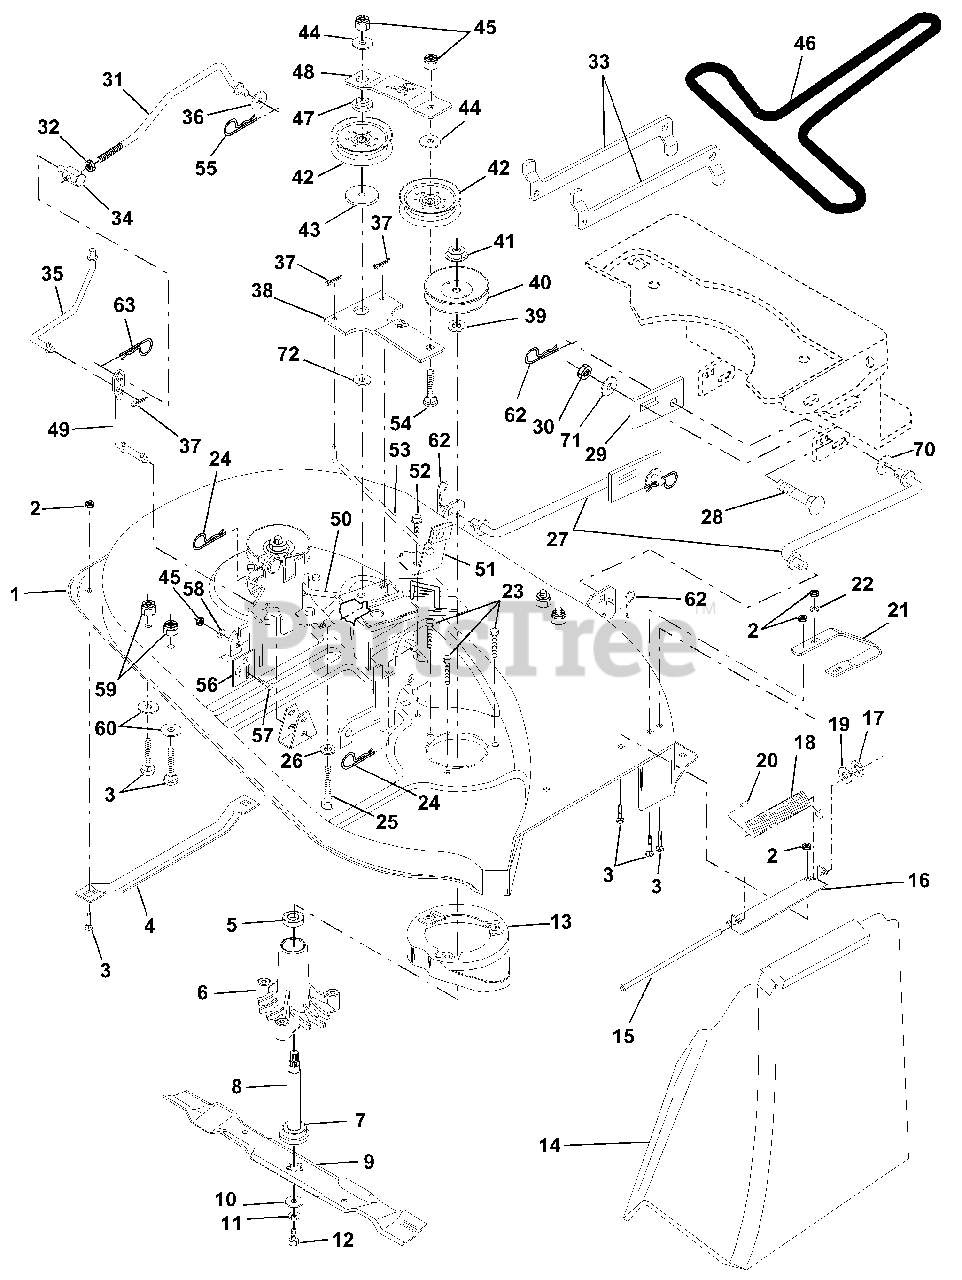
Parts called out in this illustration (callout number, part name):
1	Mower Deck Assembly
2	Nut, Lock Hx w/Ins 5/16-18
3	Bolt, Carriage 5/16-18 x 3/4
4	Runner, L.H.
6	Housing, Mandrel
8	Shaft and Bearing Assembly, Mandrel
10	Washer, Hardened
11	Washer, Lock 3/8
12	Bolt, Hex 3/8-24 x 1-1/4 Grade 8
13	Stripper, Mower, Vented
14	Shield, Deflector
15	Rod, Hinge
16	Bracket Assembly, Deflector
18	Spring, Deflector
19	Washer 11/32 x 5/8 x 16 Gauge
20	Cap, Sleeve
21	Runner, R.H.
22	Washer 11/32 x 3/4 x 16 Gauge
23	Screw Thdrol Hex Head Zinc MWR
24	Retainer, Spring
25	Bolt Hex 3/8-16 x 2-1/4
26	Washer 13/32 x 1 x 12 Gauge
27	Link Assembly, Front
28	Bolt RDHD SQNK 3/8 - 16 x 1
29	Plate Slide Link
30	Nut, Lock Hex w/washer 3/8 - 16
31	Clutch Rod, Primary
32	Nut, Hex, Jam 3/8-16
33	Arm, Suspension, Rear
34	Trunnion 3/8-16
35	Clutch Rod, Secondary
36	Washer 13/32 x 13/16 x 16 Gauge
37	Pin, Cotter 3/32 x 3/4
39	Washer .150 Thick
40	Pulley, Mandrel
41	Nut, Flangelock 9/16
42	Pulley, Flat Idler
43	Spacer, Retainer
44	Washer 13/32 x 1 x 12 Gauge
45	Nut, Lock Hex W/Ins. 3/8-16
46	Belt
47	Spacer, Idler Arm
48	Stiffener, Idler Arm
49	Rod, Pivot
50	Rod, Brake, L.H.
51	Brake Assembly
52	Screw, Hex Washer Head, Thd., Roll. 5/16-18 x 3/4
53	Rod, Brake, R.H.
54	Bolt, Carriage 3/8-16 x 1-3/4 Grade 5
55	Spring, Retainer
56	Adjustment Plate, Rear Link, L.H.
57	Bolt, Carriage 3/8-16 x 1
58	Washer 13/32 x 3/4 x 12 Gauge
59	Locknut, Hex, with Washer Insert 5/16-18
60	Washer 11/32 x 11/16 x 12 Gauge
62	Retainer Spring
63	Retainer Spring
70	Washer 1/2 x 1-1/4 x 16 Ga.
71	Washer Flat 13/32 x 1 x 10 Ga.
72	Washer Hardened
